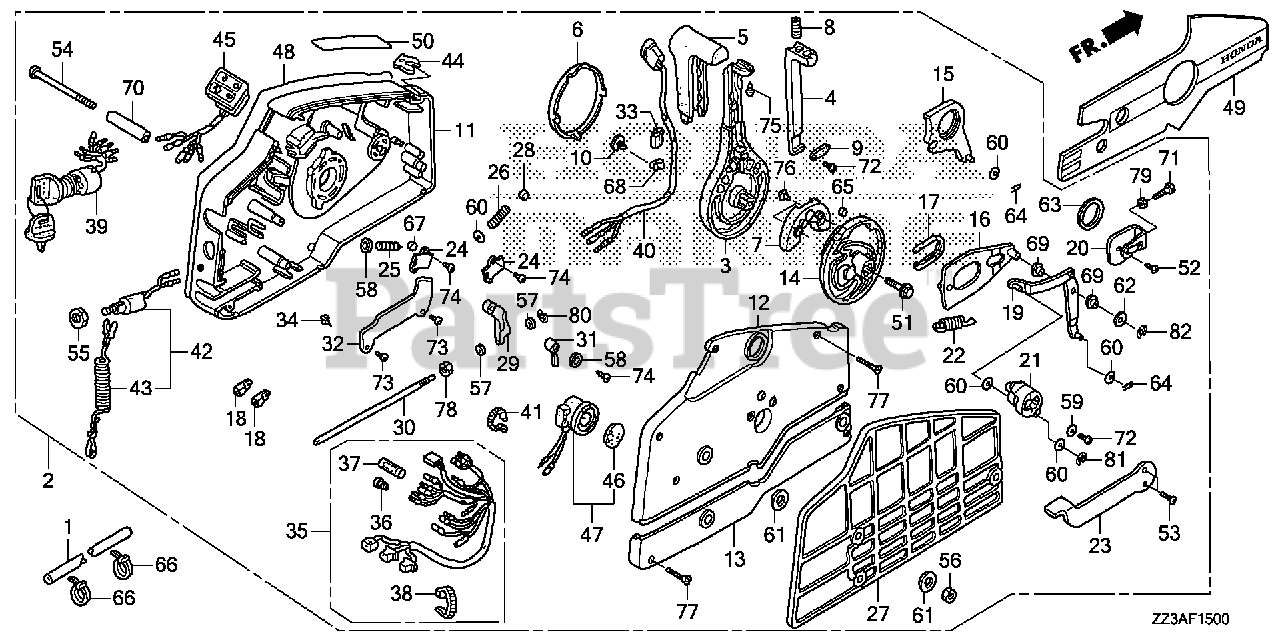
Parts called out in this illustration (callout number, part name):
1	TUBE, CORRUGATE (28MM)
2	BOX ASSY., REMOTE CONTROL (NHK MEC)
2	BOX ASSY., REMOTE CONTROL (TROLLING CONTROL)(NHK MEC)
3	HANDLE, REMOTE CONTROL
4	LEVER, HANDLE LOCK
5	GRIP, REMOTE CONTROL HANDLE
6	CAP, HANDLE
7	BLOCK, NEUTRAL LOCK
8	SPRING, REMOTE CONTROL HANDLE
9	PLATE, LEVER SETTING
10	CLAMP, HARNESS
11	HOUSING, REMOTE CONTROL BOX (A)
12	HOUSING, REMOTE CONTROL BOX (B)
13	HOUSING, REMOTE CONTROL BOX (C)
14	WHEEL, CONTROL
15	ARM, SHIFT LINK
16	PLATE, SLIDING
17	COLLAR, SLIDING PLATE
18	PIVOT, SHIFT
19	ARM, LINK JOINT
20	BRACKET, LINK JOINT
21	WHEEL, ACCELERATOR
22	SPRING, ACCELERATOR WHEEL
23	LEVER, IDLE
24	PLATE, SPRING SETTING
25	SPRING, SHIFT CLICK
26	SPRING, CHOKE RETURN
27	SPACER, REMOTE CONTROL BOX
28	SPACER, CLICK SPRING
29	BLOCK, THROTTLE FRICTION
30	BOLT, FRICTION
31	SPACER, NEUTRAL SWITCH
32	CLAMP, POWER TILT CORD
33	PIPE, HARNESS GUIDE
34	SPACER, CABLE CLAMP
35	CABLE ASSY., REMOTE CONTROL (B)
36	PLUG, CONNECTOR (INNER)
37	PLUG, CONNECTOR (OUTER)
38	TIE, CABLE (2.4X92) (NATURAL)
39	SWITCH ASSY., COMBINATION
40	SWITCH ASSY., POWER TRIM-TILT
41	BAND (BLACK 3.5X140)
42	SWITCH ASSY., EMERGENCY STOP
43	WIRE, EMERGENCY
44	CLIP, EMERGENCY LOCK
45	LAMP ASSY., INDICATION
46	PLATE, TURN SIGNAL BUZZER
47	BUZZER, WARNING
48	PLATE, REMOTE CONTROL (COUTION COLOR=RED & YELLOW)
49	PLATE, REMOTE CONTROL (REVERSE)
50	MARK, FAST IDLE
51	BOLT, FLANGE (8X35)
52	SCREW, PAN (6X10)
53	SCREW, FLAT (5X12)
54	SCREW (6X95)
55	NUT, HEX. (16MM)
56	NUT, HEX. (6MM)
57	WASHER, PLAIN (4MM)
58	WASHER, PLAIN (5MM)
59	WASHER, PLAIN (5MM)
60	WASHER, PLAIN (6MM)
61	WASHER (6MM)
62	WASHER, PLAIN (8MM)
63	WASHER (28MM)
64	PIN, LOCK (6MM)
65	PIN (6X6)
66	BAND, SELF-LOCK
67	ROLLER, CLICK
68	CLIP, WIRE HARNESS (6.3MM)
69	COLLAR, LINK JOINT
70	COLLAR, DISTANCE (6X10X43.5)
71	BOLT, HEX. (5X16)
72	SCREW, PAN (5X10)
73	SCREW, TAPPING (5X8)
74	SCREW, TAPPING (5X10)
75	SCREW, TAPPING (5X12)
76	SCREW, TAPPING (6X16)
77	SCREW, TAPPING (5X25)
78	NUT, HEX. (6MM)
79	NUT, HEX. (5MM)
80	E-RING (3MM)
81	E-RING (4MM)
82	E-RING (7MM)
